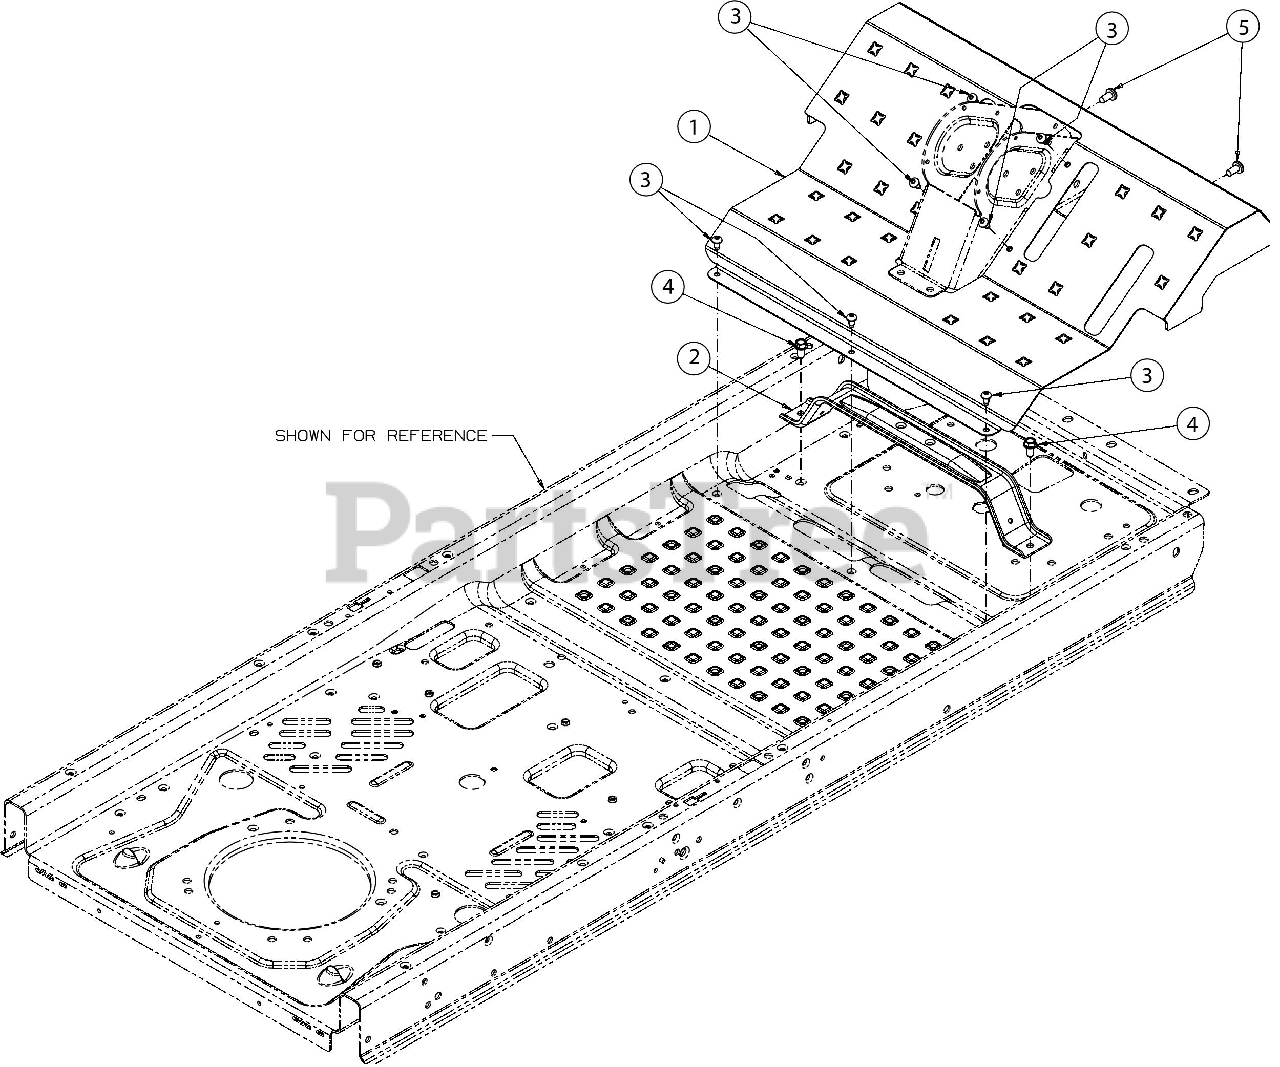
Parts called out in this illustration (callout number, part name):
1	FLOORBOARD-
2	STEERING SUPPORT BRACKET
3	SCREW 1/4-20 X .500
4	SCREW 5/16-18 X .750
5	SCREW 5/16-18 X .750
